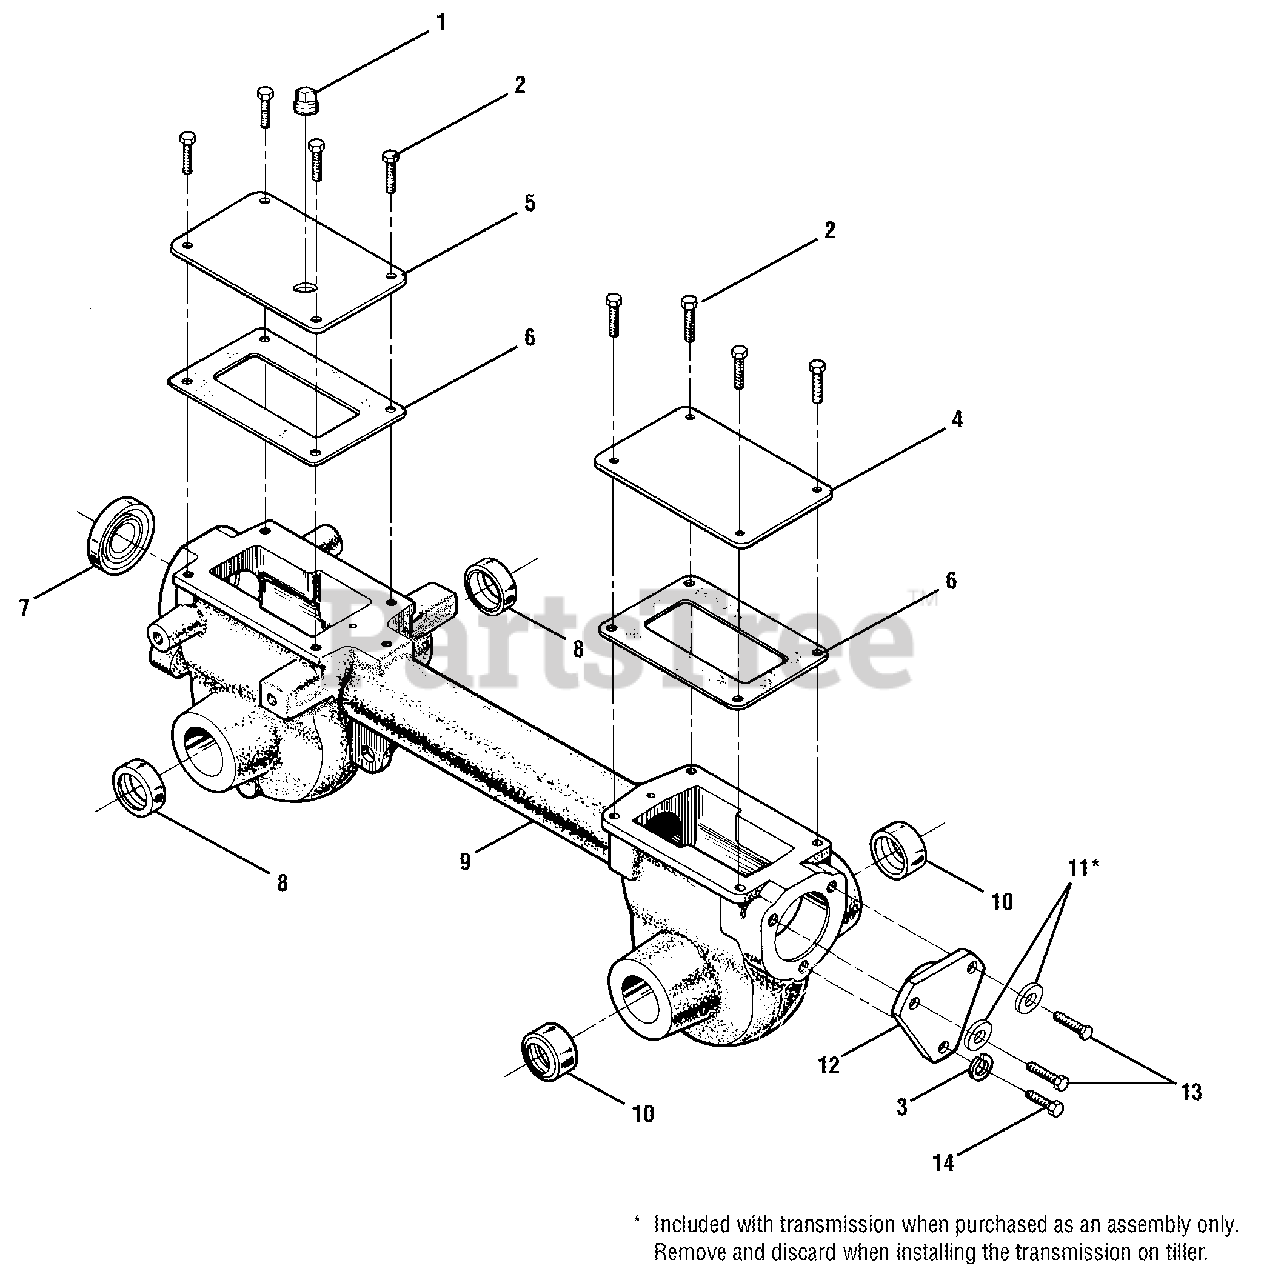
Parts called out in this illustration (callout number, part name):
1	Plug, Transmission Oil Fill
2	Hex Hd. Flange Screw, 5/16-18 x 5/8,Gr. 5
3	Lock Washer, 5/16
4	Rear Cover, Transmission
5	Front Cover, Transmission
6	Gasket, Housing Cover
7	Oil Seal, Drive Shaft
8	Oil Seal, Wheel Shaft
9	Transmission Housing Assembly
10	Oil Seal, Tine Shaft
11	Washer, Flat, .344 x .750 x .120
12	Rear Bearing Cap
13	Hex Hd. Flange Screw, 5/16-18 x 1
14	Hex Hd. Flange Screw, 5/16-18 x 3/4
